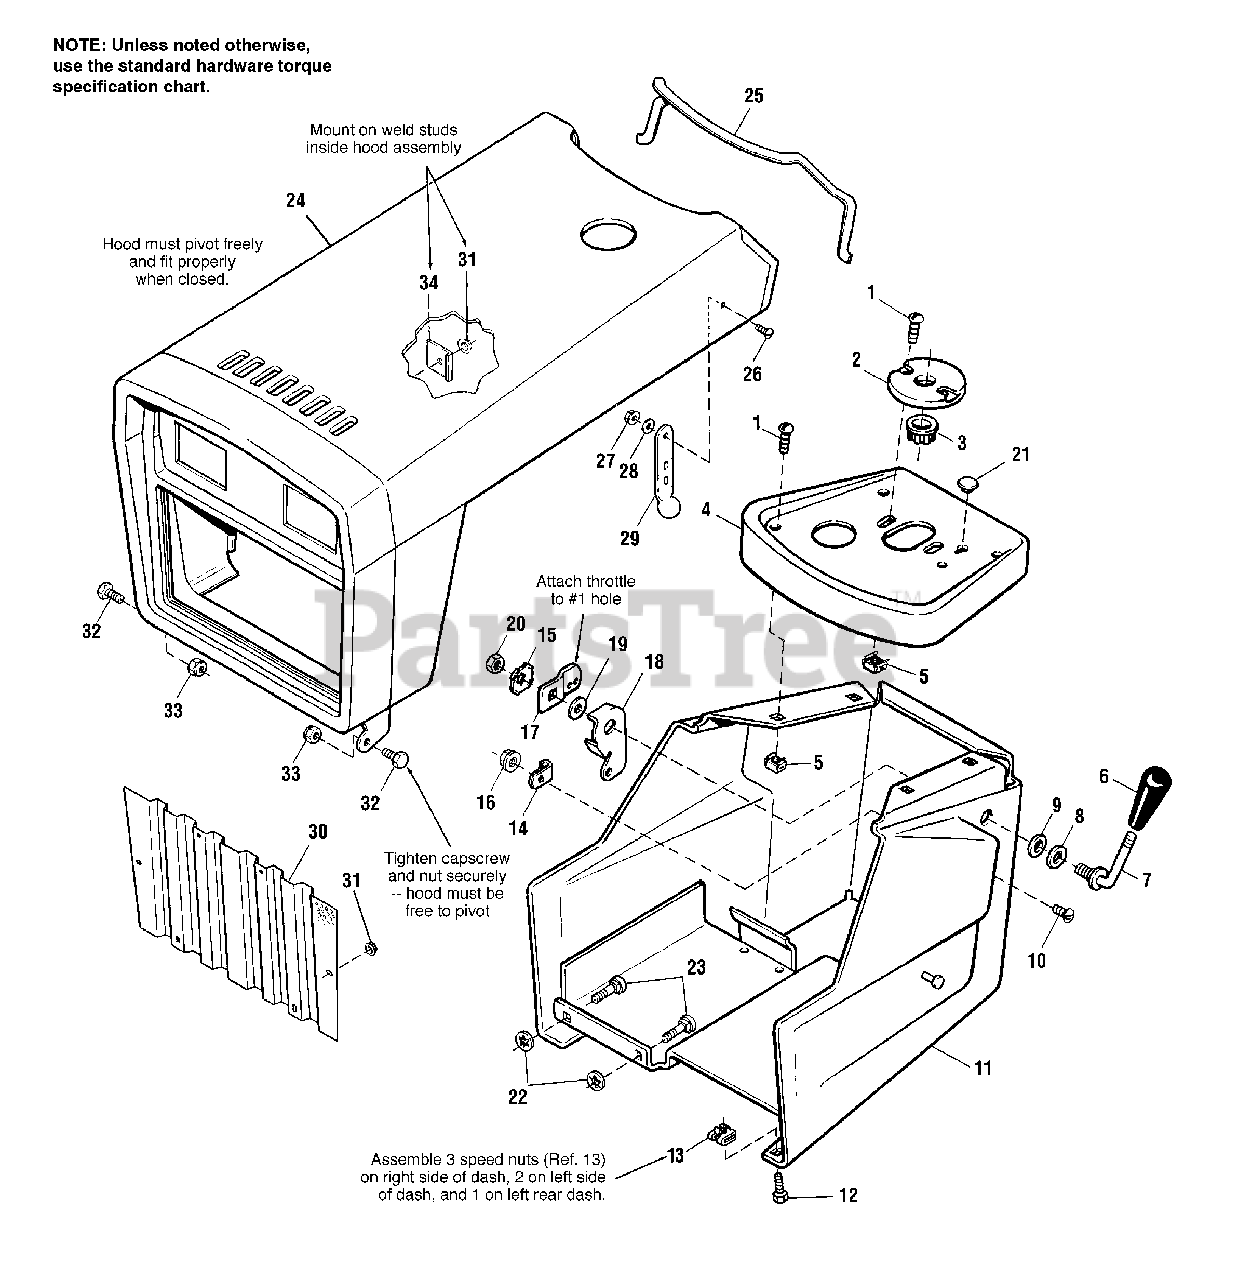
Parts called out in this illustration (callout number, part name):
1	CAPSCREW, Machine, Round Hd, 1/4-20 x 1/2
2	PLATE, Adjusting, Steering
3	BUSHING
4	PANEL, Instrument
5	SPEED NUT, Tinnerman
7	HANDLE, Throttle Control
10	CAPSCREW, Truss Hd, #10-32 x 1/2
11	DASH ASSEMBLY
12	CAPSCREW, Hex, Self-Tapping, #14AB x 3/4
13	NUT, Speed
14	CLIP, Control Cable
15	LOCKWASHER, Dished Type, 3/8
16	NUT, Hex, Washer, #10-32
17	ARM, Throttle
18	STOP, Throttle
20	LOCKNUT, Hex, 3/8-16
21	PLUG, Button
22	PUSH NUT
23	CARRIAGE BOLT, 5/16-18 x 3/4
24	HOOD & GRILLE ASSEMBLY, Orange
24	HOOD & GRILLE ASSEMBLY, Red
25	MOULDING, Hood
26	CAPSCREW, Truss Hd, #10-32 x 1/2
27	LOCKNUT, Hex, #10-32
28	WASHER
29	STRAP, Hood
31	LOCKNUT, Pal
32	CAPSCREW, Hex Hd, 3/8-16 x 1
33	LOCKNUT, Hex, 3/8-16
34	CLIP, Headlight Mounting
